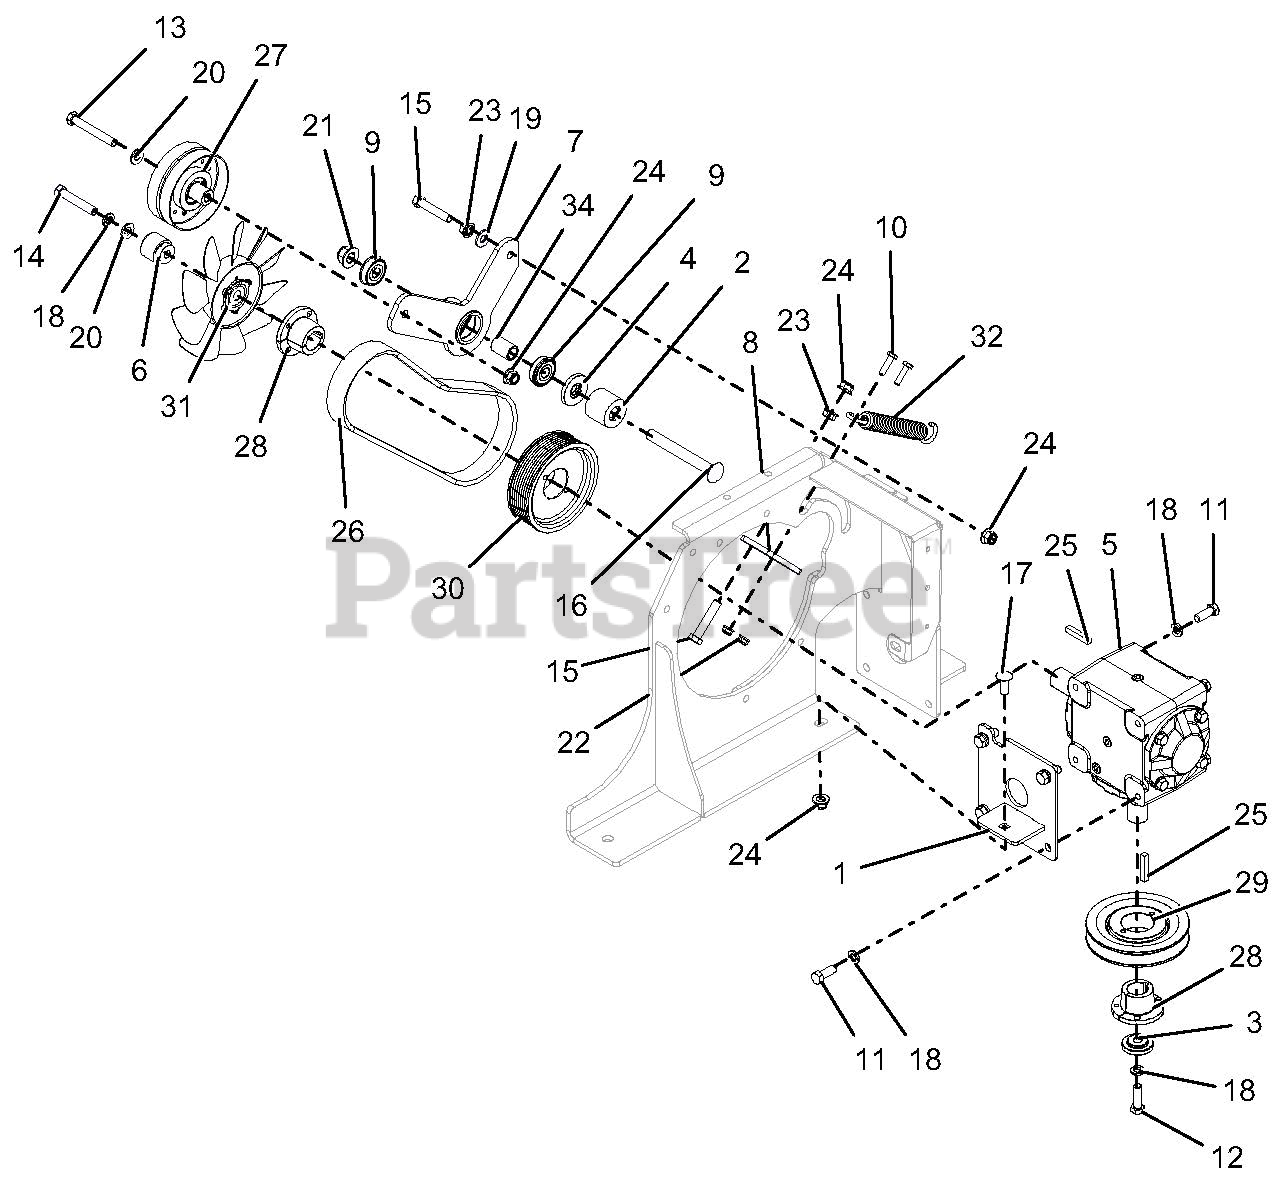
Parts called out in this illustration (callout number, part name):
1	WDMT, GEARBOX ENGINE MOUNT
2	SPACER, IDLER ARM MOUNT
3	RETAINER, SHEAVE
4	SPACER, IDLER ARM
5	GEARBOX, 90 DEG. 1:1 215HD
6	HUB, FAN SPACER
7	WDMT, DIESEL IDLER ARM
8	PLATE, SPRING ANCHOR
9	BRG-BALL .50X1.38X.438 SEALED
10	@BLT-HEX .25-20X1.00 GR5 YWZC
11	@BLT-HEX .38-16X1.00 GR5 YWZC
12	@BLT-HEX .38-16X1.25 GR5 YWZC
13	@BLT-HEX .38-16X2.75 GR5 YWZC
14	@BLT-HEX .38-16X2.25 GR5 YWZC
15	BLT-HEX .38-16X2.00 GR8 YWZC
16	BLT-RDHDSQNK .50-13X4.50 G5 Y
17	@BLT-RDHDSHSQNK.38-16X1.0 G5YZ
18	@WSHR-LK .38X.094 REG YWZC
19	@WSHR-FL-STL.38X.875X.083 YWZC
20	@WSHR-FL-STL.406X.812X.065 YWZ
21	@NUT-LK-NYL-FLG .50-13 YWZC
22	@NUT-LK-NYL-FLG .25-20 YWZC
23	@NUT-SPNLK-FLG .375-16 YWZC
24	@NUT-LK-NYL-FLG .38-16 YWZC
25	KEY-SQ .25 X 1.50 X .25 SAE
26	BELT, 8-RIB POLY-V
27	PLY, IDLER FLAT 4.00 X .38
28	BUSHING,TAPER, 1" SHAFT
29	SHEAVE,TAPER BSHG, 4.95" OD
30	SHEAVE, PVK 8-RIB 4.650 DIA.
31	FAN, 7" 10 BLADE W/ INSERT
32	SPRING- EXTENSION
34	SPACER .510 X .867 X 1.1485
